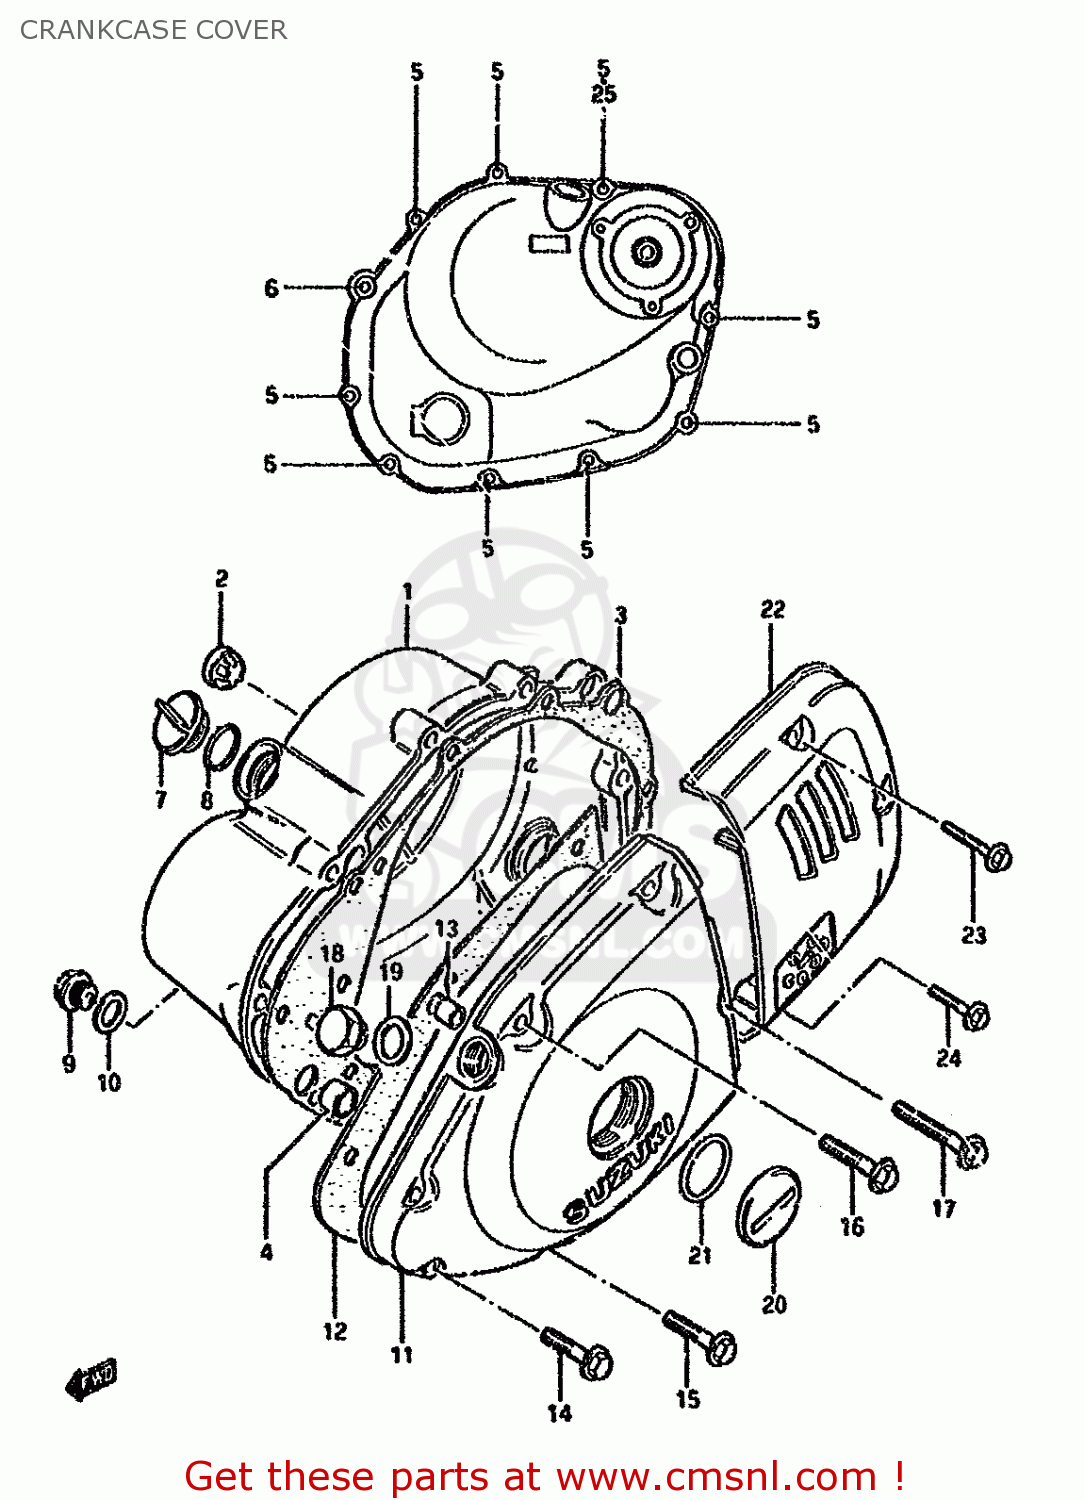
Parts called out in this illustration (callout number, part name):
1	COVER,CLUTCH
2	LENS,OIL LEVEL CHECK
3	GASKET,CLUTCH COVER (NAS)
4	PIN
5	BOLT
6	BOLT
7	PLUG(20X10)
8	O RING(D:3.1,ID:16.8)
9	PLUG(14X12)
10	GASKET(13.8X18.8X4.8) (NAS)
11	COVER,MAGNETO
12	GASKET,MAGNETO COVER (NAS)
13	PIN
14	BOLT
15	BOLT
16	BOLT
17	BOLT
18	PLUG,12X9
19	GASKET(12.1X16.2X3.7) (NAS)
20	PLUG(26X9)
21	O RING(D:3.1,ID:22.7)
22	COVER,SPROCKET
23	BOLT
24	BOLT
25	GASKET(5.8X13X1.2) (NAS)
